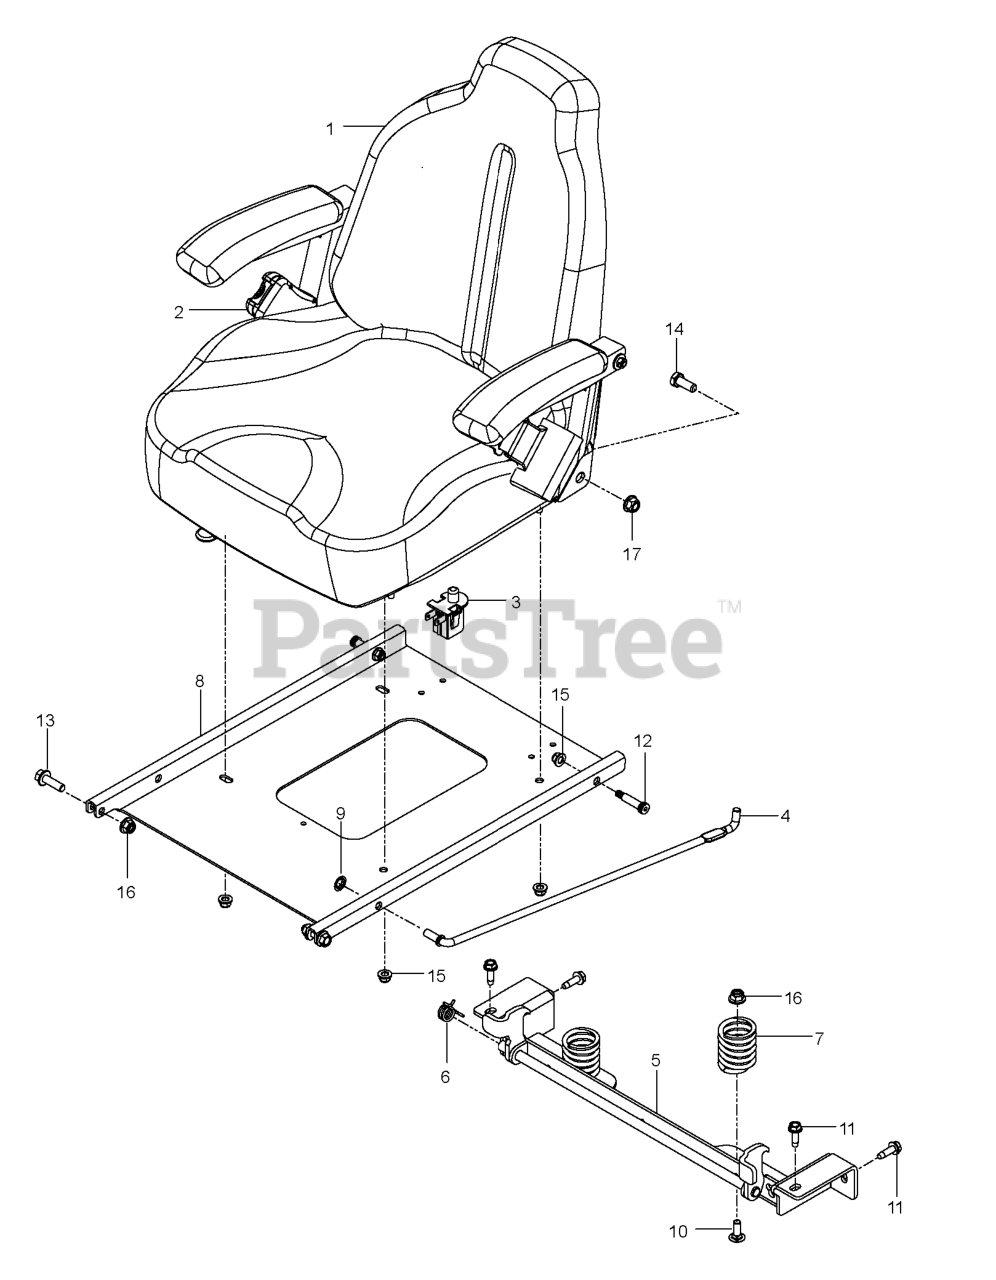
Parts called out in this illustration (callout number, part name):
1	SEAT.ASM.907.TRACK.W/BELT
2	BELT, SEAT
3	SEAT SWITCH
5	BRACKET.PNT.LTCH.SEAT.WELD.SPR
6	SPRING, TORSION
7	SPRING, SEAT
8	PAN, SEAT, BLACK
9	NUT 3/8 PALNUT RTNG BLK PHOS
10	RHSNB 3/8C X 1
11	RP BLT 5/16-18 X 1 THRD FORM D
12	BOLT, SHOULDER 3/8 X 1.25
13	HHFS 3/8-16 X 1.25 GD 5
14	BOLT FIN HEX 7/16-14 X 1
15	5/16-18 NYLOC FLANGE NUT
16	NUT 3/8-16 HEX FLG NYLOC ZD
17	NUT 7/16-14 HEX WHIZ LK
